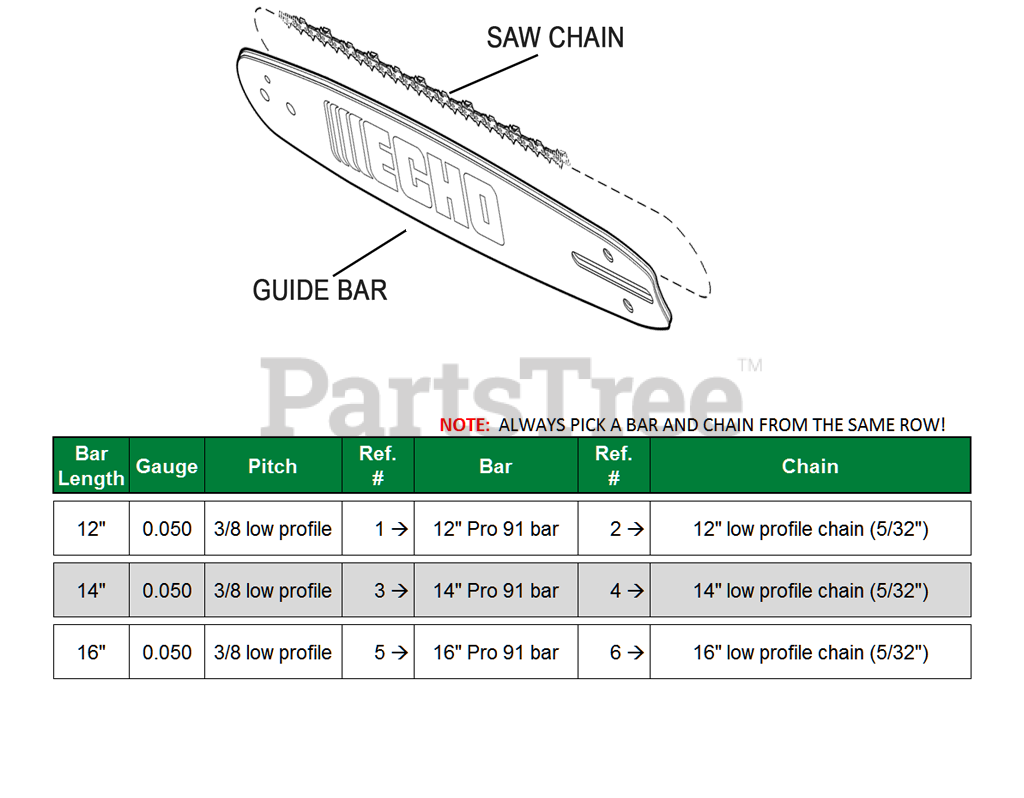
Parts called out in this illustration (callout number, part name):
1	12" Pro 91 bar
2	12" low profile chain (5/32")
3	14" Pro 91 bar
4	14" low profile chain (5/32")
5	16" Pro 91 bar
6	16" low profile chain (5/32")
